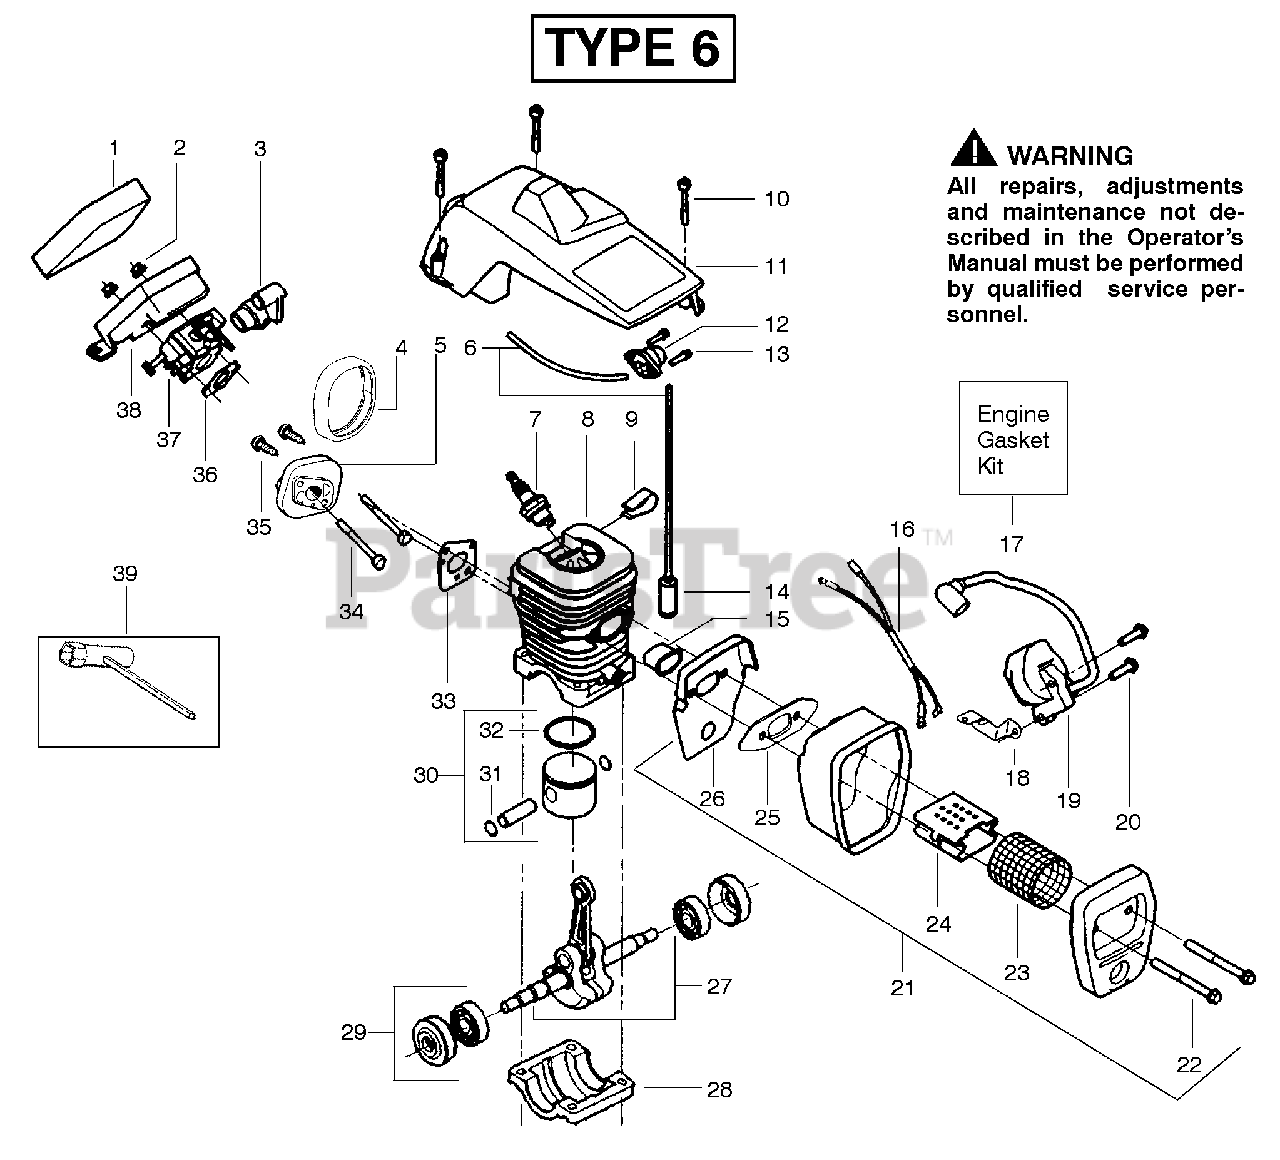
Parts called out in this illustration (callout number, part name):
1	Foam- Air Filter
3	Grommet-Carb Adjust
4	Seal-Carb Adapter
5	Carb. Adapter
6	Fuel Line Kit
7	Spark Plug
8	Kit-Cylinder
9	Clip-High Tension Lead
11	Cylinder Shield
12	Air Purge Ass’y.
14	Fuel Pick-up Ass’y.
15	Heat Insulator
16	Assy. -Wire Harness
17	Kit-Engine Gasket
18	Strap-Ground
19	Module- Ignition
21	Assy-Muffler
23	Screen-Spark
24	Diffuser-Muffler
25	Gasket-Muffler
26	Backplate-Muffler
27	Assy. - Crankshaft
28	Cap-Crankcase
29	Assy.-Seal & Bearing
30	Kit-Piston
31	Retainer-Piston Pin
32	Ring - Piston
33	Gasket - Carb. Adapter
36	Gasket - Carburetor
37	Kit-Carburetor
38	Housing- Air Filter
39	Wrench - Bar
